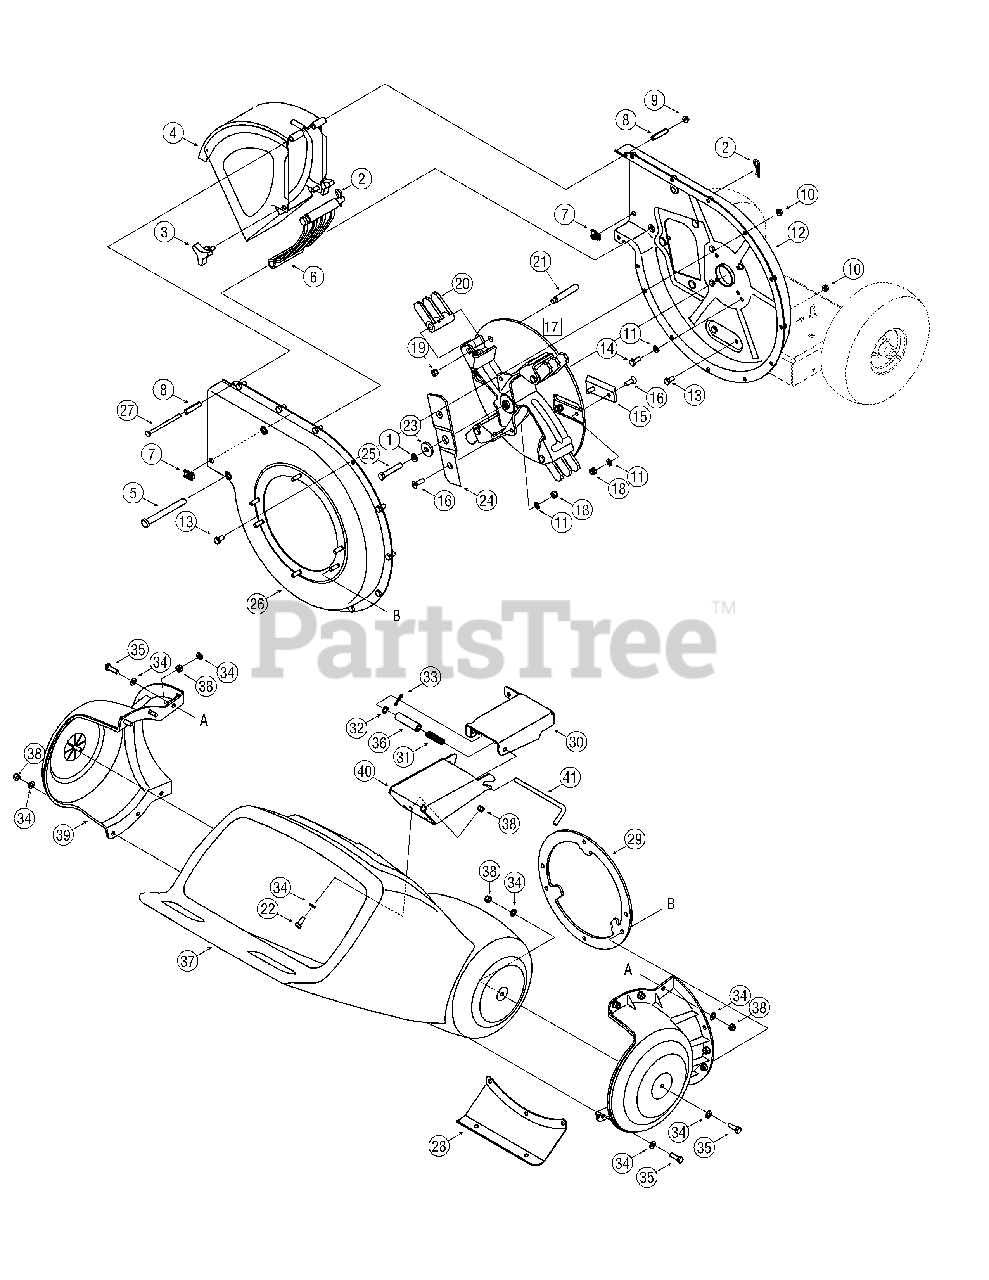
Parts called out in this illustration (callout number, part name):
1	Lock Washer, 3/8
2	Cotter Pin
3	Wing Knob 5/16-18
4	Chute Deflector Assembly
5	Clevis Pin
6	Shredder Screen
7	U-Nut 5/16-18
8	Spacer
9	Hex Lock Nut, 1/4-20
10	Hex Lock Nut 5/16-18
11	Lock Washer 5/16
12	Inner Impeller Housing Assembly
13	Hex Cap Screw 5/16-18 x.625
14	Hex Cap Screw 5/16-24 x .75
15	Chipper Blade
16	Hex Cap Screw 5/16-24 x 1.0
17	Impeller Assembly
18	Hex Lock Nut 5/16-24
19	Nut, Jam Lock, 3/8-16
20	Flail Blade
21	Shoulder Pin, .5 x 2.625
22	Hex Cap Screw 5/16-18 x .75
23	Flat Washer 3/8 x 1.25
24	Shredder Blade
25	Hex Cap Screw 3/8-24 x 2.25
26	Outer Impeller Housing Assembly
27	Hex Cap Screw 1/4-20 x 3.75
28	Front Support Bracket
29	Shredder Plate
30	Rear Hopper Bracket Assembly
31	Compression Spring 1.75
32	Flat Washer
33	Cotter Pin
34	Flat Washer.330 ID x .630 OD
35	Hex Cap Screw 5/16-18 x 1.0
36	Spacer, .375 ID x 2.50 LG
37	Hopper Assembly
38	Hex Lock Nut 5/16-18
39	Hopper Collar
40	Front Hopper Bracket Assembly
41	Lock Rod
